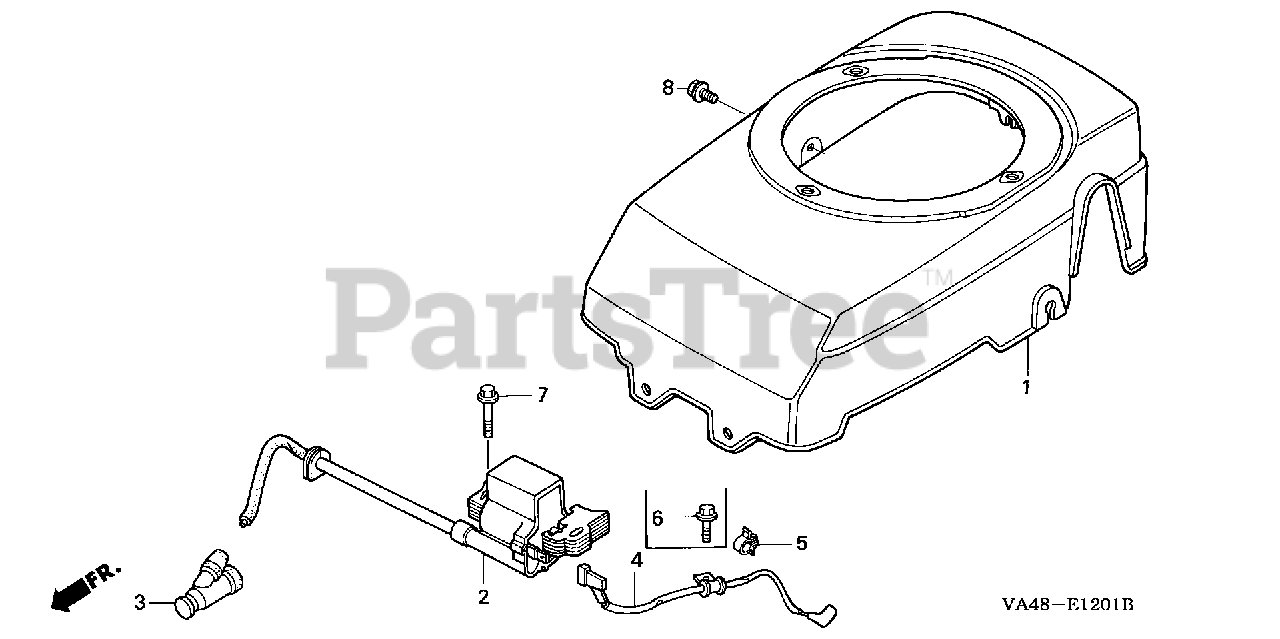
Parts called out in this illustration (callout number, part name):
1	COVER, FAN *R8* (BRIGHT RED)
2	COIL ASSY., IGNITION
3	TERMINAL ASSY., IGNITION
4	WIRE, STOP SWITCH
4	WIRE, STOP SWITCH (NOT AVAILABLE)
5	HOLDER, STOP SWITCH WIRE Use up to Engine SN 2056819.
5	CLAMP, BRAKE PIPE (GRAY)
6	BOLT, FLANGE (5X10)
7	BOLT, FLANGE (6X25) Use up to Engine SN 2056819.
8	BOLT, FLANGE (6X10)
